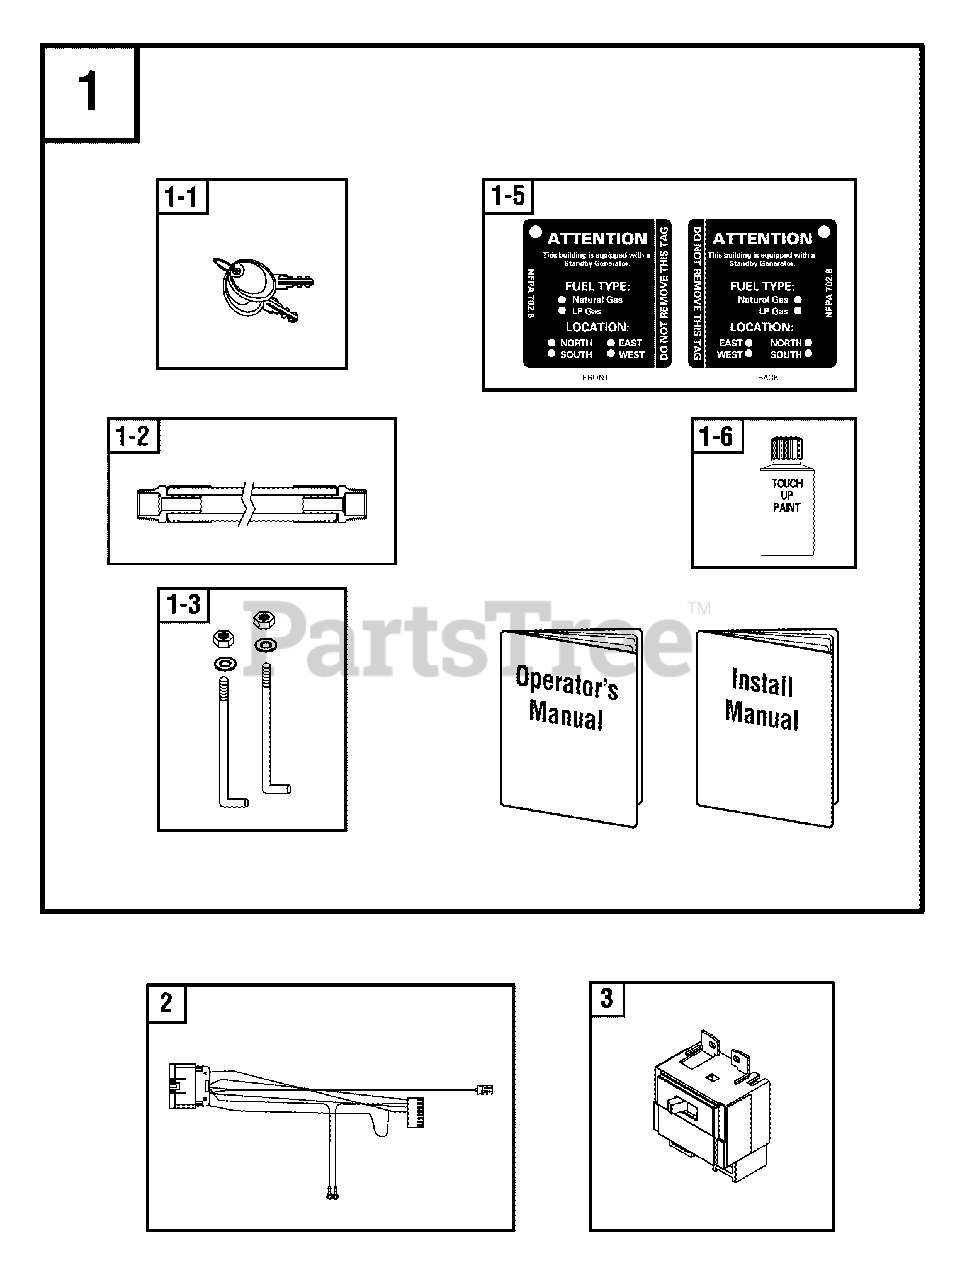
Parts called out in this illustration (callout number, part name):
1	KIT-MANUAL, ACC
1-3	KIT-HOLD DOWN, BATTERY
1-5	DECAL-ATTN STANDBY EQUIPMENT
1-6	PAINT-TOUCH-UP, ALMOND TEXTURE
3	BREAKER-CIRCUIT
